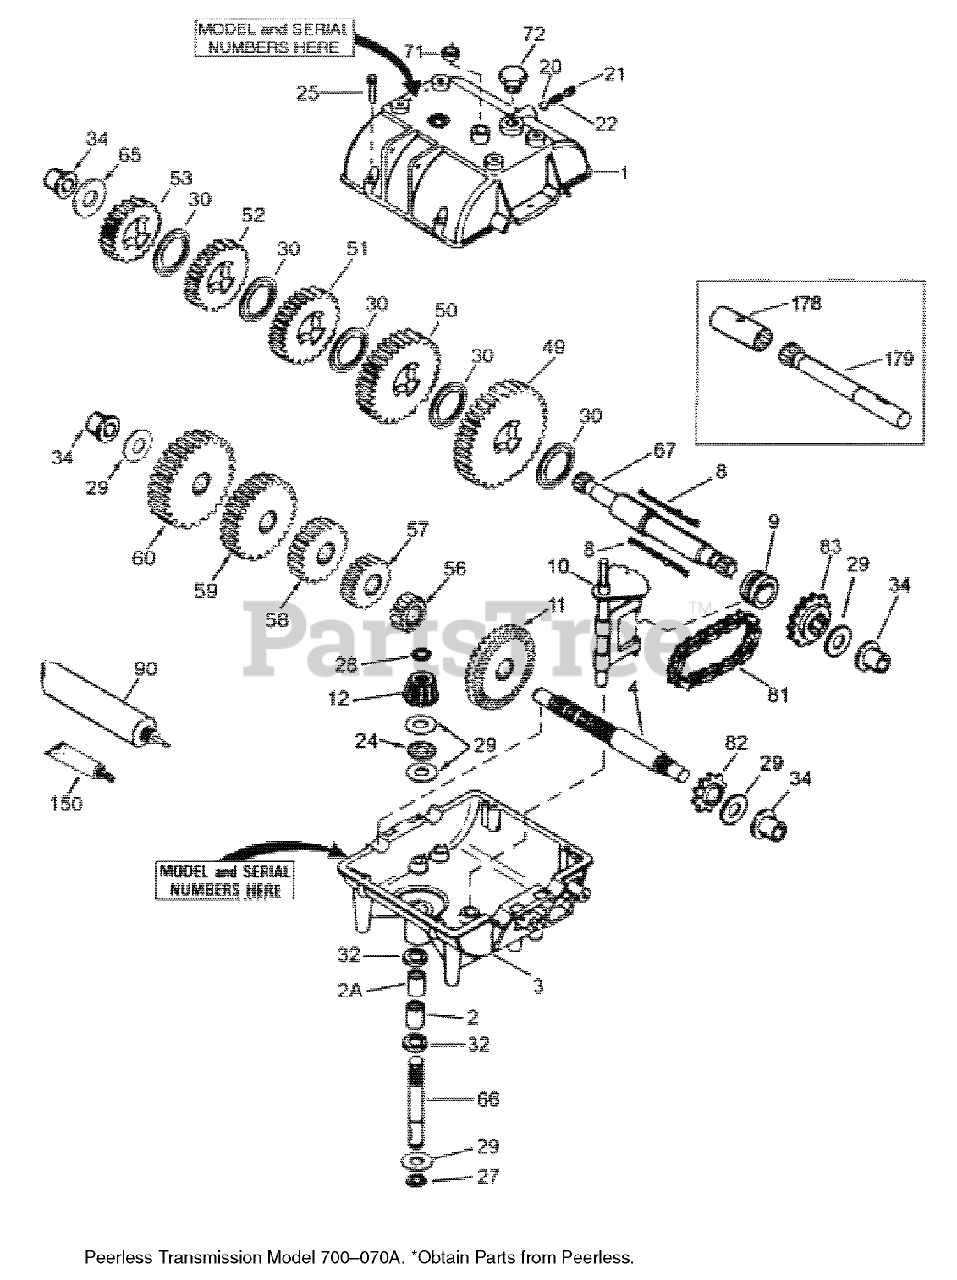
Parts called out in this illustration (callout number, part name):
1	Cover-Transmission
2	Bearing-Needle
2A	Bearing-Needle
3	Case-Transmission
4	Countershaft
8	Key
9	Collar-Shift
10	Shift Rod Fork
11	Gear-Bevel, 42 teeth
12	Bevel Pinion (14 Teeth-Steel)
20	Ball-Steel
21	Screw-Set
22	Spring
24	Bearing-Thrust
25	Screw
27	Ring-Snap
28	Ring-Retainer
29	Washer
30	Washer
32	O Ring
34	Bushing-Flange
49	Gear-Spur, 37 Teeth
50	Gear-Spur, 35 Teeth
51	Spur Gear (32 Teeth-Steel)
52	Gear-Spur, 30 Teeth
53	Gear-Spur, 25 Teeth
56	Gear-Spur, 12 Teeth
57	Gear-Spur, 15 Teeth
58	Spur Gear (18 Teeth-Steel)
59	Gear-Spur, 20 Teeth
60	Gear-Spur, 25 Teeth
65	Washer
66	Shaft-Input
67	Shifter and Brake Shaft
71	Cut Seal-Square
72	Plug
81	Chain-Roller #41
82	Sprocket-9 Teeth
83	Sprocket-18 Teeth
90	Grease 32 Oz
150	Gasket Eliminator
178	Coupling (Optional)
179	Connector Shaft(Optional)
